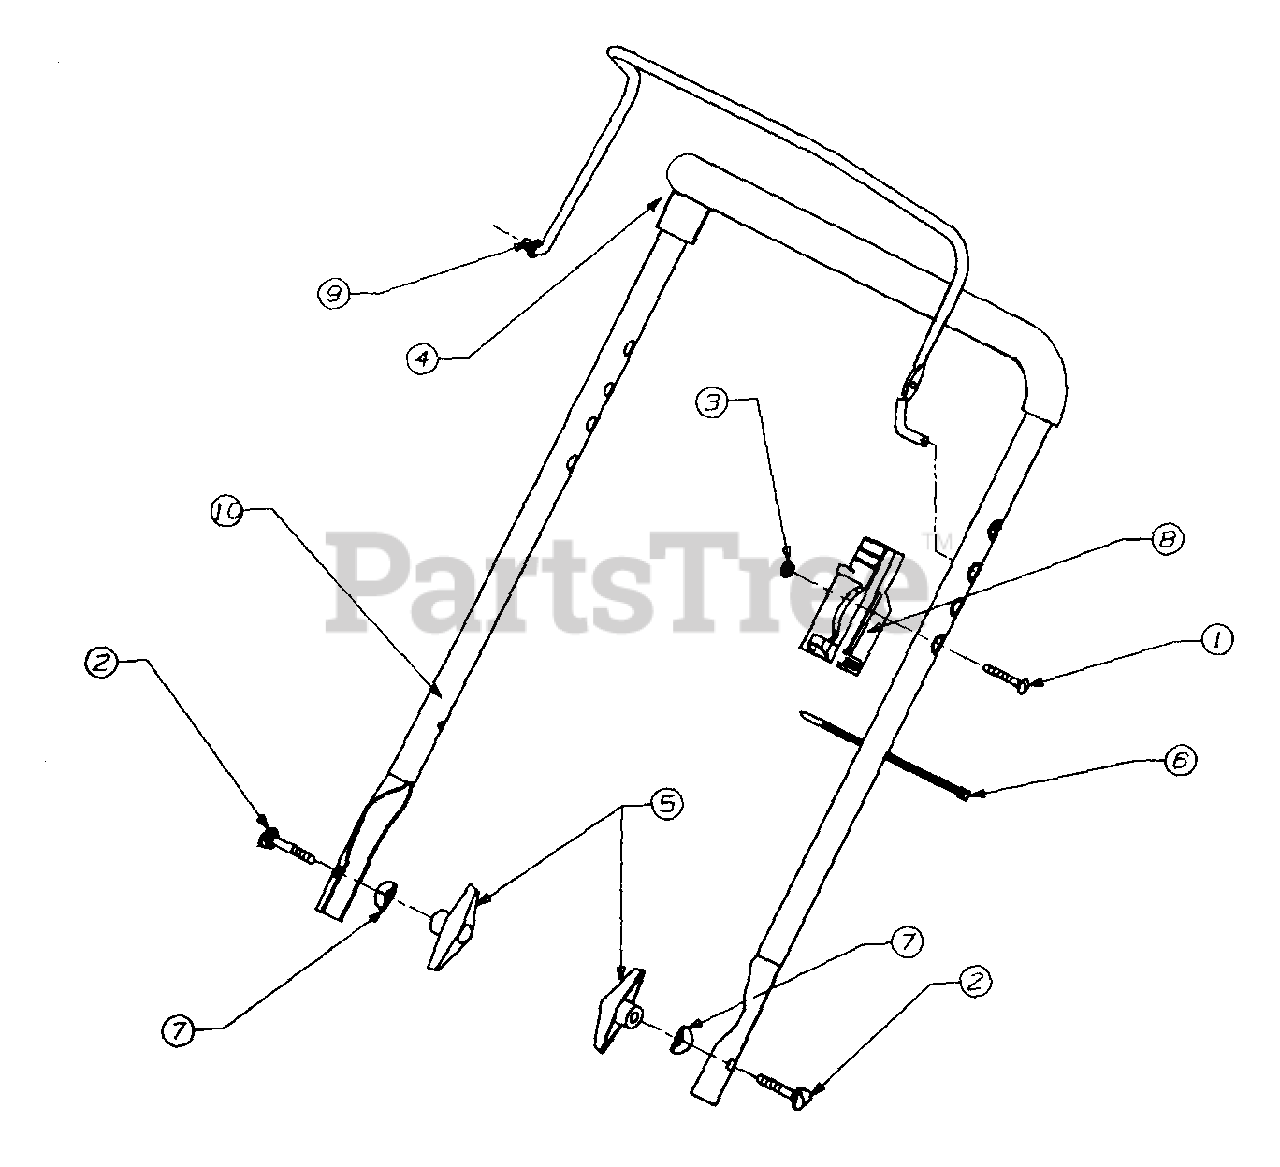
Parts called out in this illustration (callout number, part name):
1	Screw, Machine Oval Hd.
2	Bolt, Carriage 5/16-18 x 2"
3	Nut, Hex 1/4-20 Thd.
4	Foam Grip Handle 22"
5	Knob
6	Cable Tie
7	Washer, Saddle
8	Housing
9	Lever, Control
